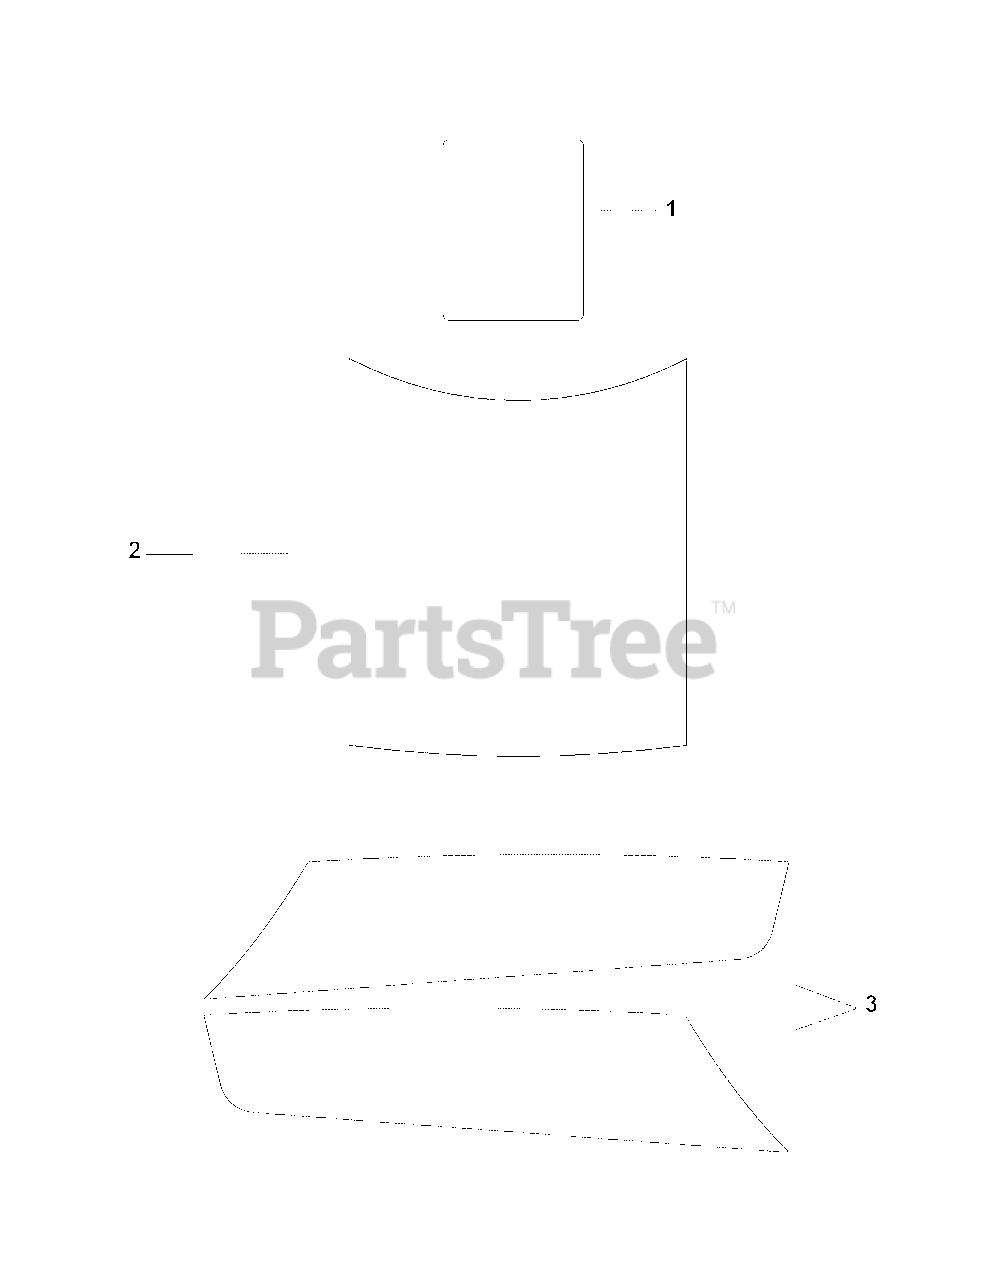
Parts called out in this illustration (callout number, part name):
1	Decal, Clear Laminate
2	Decal, 20Hp
3	Decal, Wing Set
